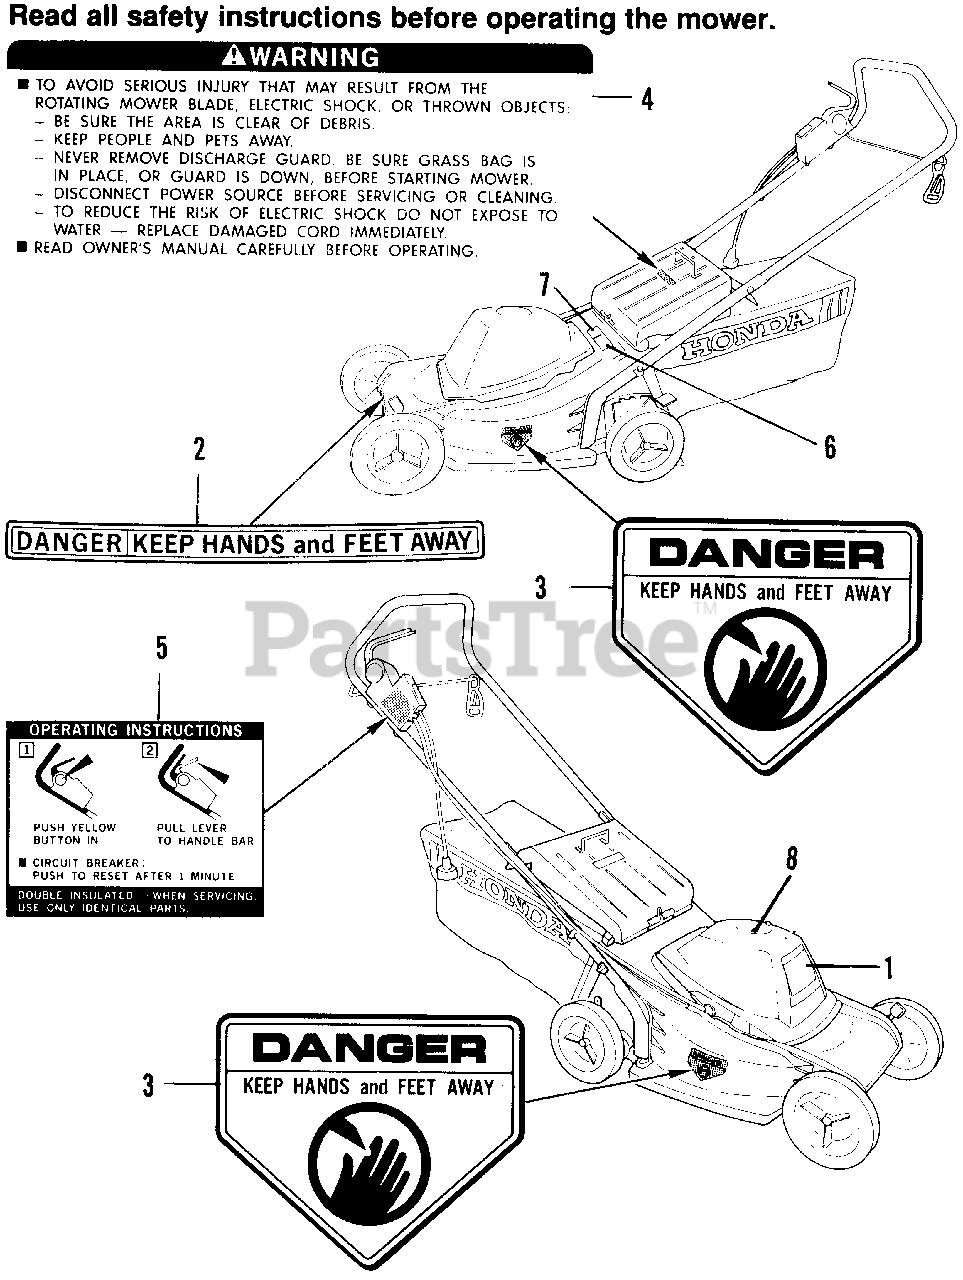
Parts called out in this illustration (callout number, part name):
1	LABEL (HR17)
2	MARK A, HOUSING DANGER (E)
3	LABEL C, HOUSING CAUTION
4	LABEL, DISCHARGE WARNING
5	MARK, SWITCH OPERATION
6	MARK, MFG. (NOT AVAILABLE)
7	MARK, UL (NOT AVAILABLE)
8	LABEL, TOP COVER
